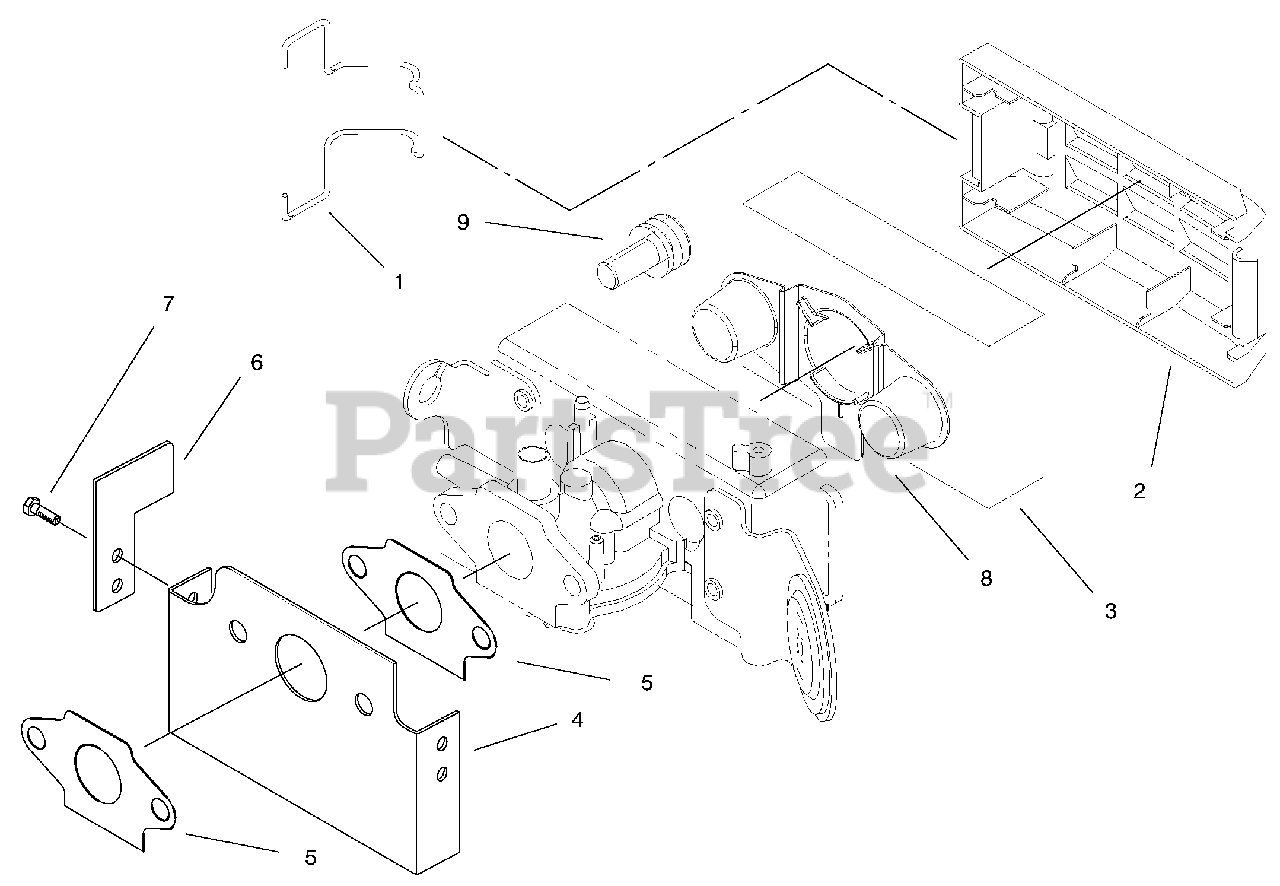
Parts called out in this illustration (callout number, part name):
1	Retainer-Cover
2	Cover-Air Filter
3	Element-Air Filter
4	Shield-Carburetor (Int'l)
5	Gasket-Carb.
6	Shield-Governor F (Int'l)
8	Shield-Fuel
